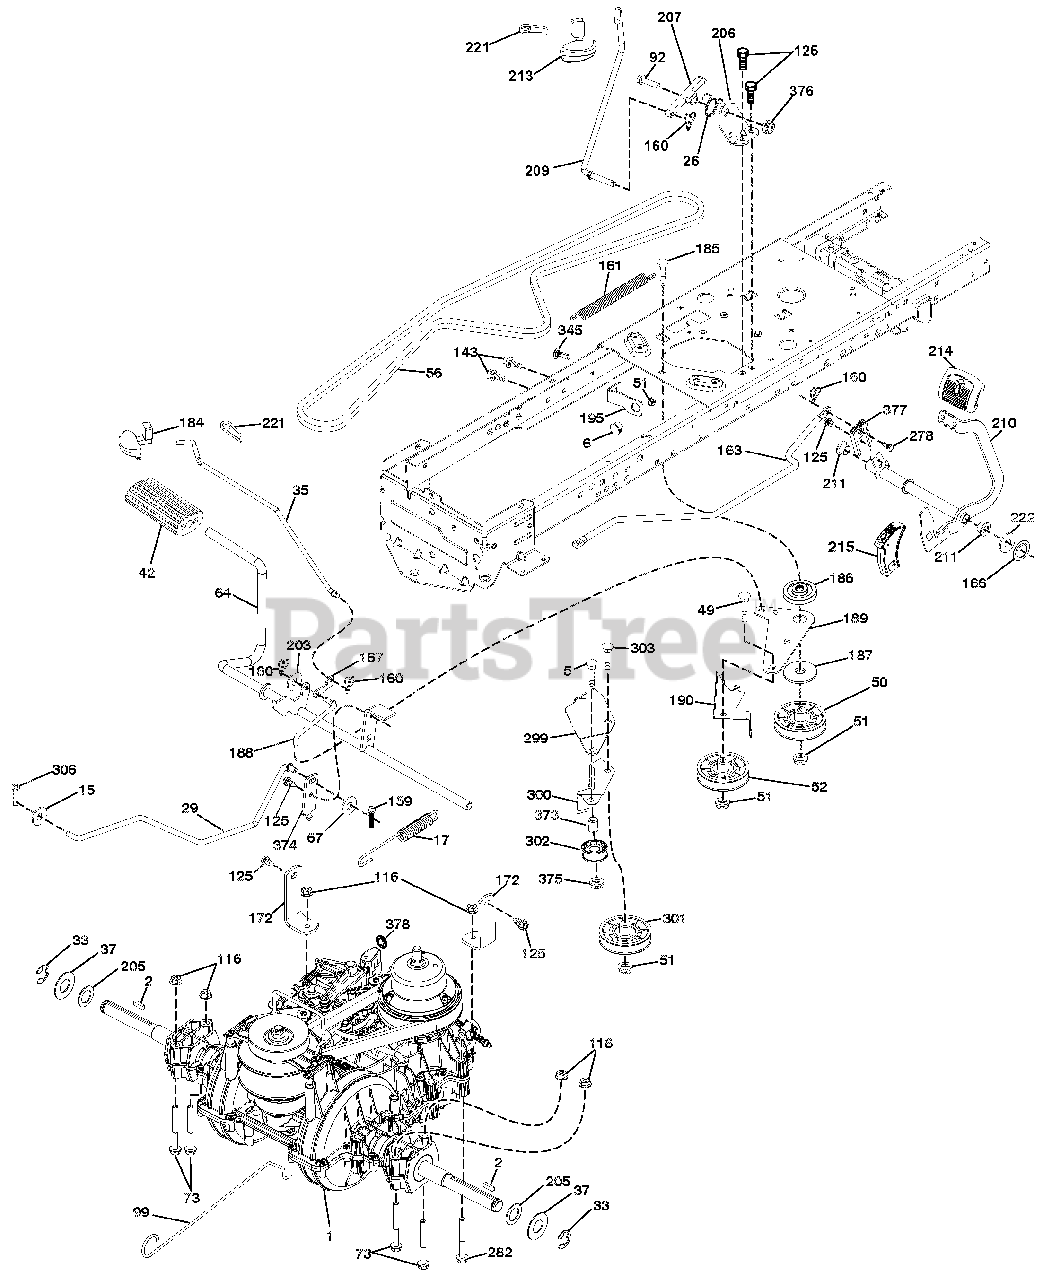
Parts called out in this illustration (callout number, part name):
1	TRANSAXLE, VARIATOR SD PEDAL (580486201)(ORDER PARTS FROM TRANSAXLE MANUFACTURER.)
2	KEY.SQUARE.2.0 X .1845/.1865
5	BOLT.HEX.HS.3/8-16.UNCX2-1/4
6	Bushing Snap Nyl Blk Fuel Line
15	WASHER.13/32 X 13/16 X 16 GA.
17	SPRING BRAKE
26	SPRING.RETURN.CRUISE
29	ROD BRAKE
33	E-RING.#5133-75
35	ROD.BRAKE.PARKING.LT.TEX
37	WASHER.HARDEN..793 X 1.637X060
42	COVER PEDAL BLK ROUND
49	BOLT.RDHD.3/8-16UNCX1-3/4.GR5
50	IDLER.FLAT.910"OFFSET
51	Nut, Hex, Flangelock 3/8-16
52	IDLER.V-GROOVE.910"OFFSET
56	BELT.DRIVE.100.97"
64	SHAFT ASM. PEDAL BRAKE
67	Washer 13/32 x 13/16 x 12 Ga.
73	BOLT.HEX.FLGHD.5/16-18.GR.5
92	Bolt, Hex Head 5/16-18 x 1-1/4
99	ROD.BYPASS
116	Nut, Lock Hex Flange 5/16-18 u
125	SCREW.5/16-18X3/4.SMGML.TAP/BL
143	SCREW.THDROL.5/16-18 X 1/2TYTT
159	PIN.COTTER.1/8 X 3/4.CAD.
160	RETAINER.CLIP(M).DIA.290
161	SPRING.RETURN.CLUTCH.6.75
163	ROD CONTROL PEDAL
166	NUT PUSH .625
167	LATCH.BRAKE.PARKING
172	STRAP TORQUE VARIATOR
184	HANDLE.PARKNG.BRAKE.LT.TEX.667
185	BOLT.RDHD.3/8-16UNC X2-3/4 GR5
186	SPACER.RETAINER
187	WASHER.13/32 X 2 X 10 GA.
188	LINK.CLUTCH.GROUND DRIVE
189	BELLCRANK.GROUNDRIVE.NSTG/NSTL
190	KEEPER.BELLCRANK.DRIVE.GROUND
195	BRACKET.BRAKE
203	Washer 11/32 x 11/16 x 16 Ga.
205	WASHER.25/32 X 1-5/8 X 16GA.
206	BRACKET MOUNT LATCH CRUISE
207	LATCH CONTROL CRUISE
209	ROD.CONTROL.CRUISE
210	WELDMENT PEDAL
211	BEARING.NYLON.BLK..629 ID.
213	KNOB.CONTROL.CRUISE
214	PAD PEDAL FORWARD
215	CAP PEDAL REVERSE
221	RETAINER.SPRING.CLIP.HANDLE
222	WASHER.21/32X1-1/4.10GA.N/PLTD
278	BOLT CRUISE VARIATOR
282	BOLT.HEX. 5/16-18 X 3 GR. 5
299	Bracket Mount Idler
300	Keeper Idler Rear
301	Pulley Idler V-Groove
302	PULLEY,IDLER.FLAT
303	Bolt Rdhd Sgnk 3/8-16 x 2-1/4
306	Pin Cotter 1/8 x 1 Cad
345	Bolt Rdhd Sht Sqnk 3/8-16 x 3/
373	SPACER.IDLER
374	ARM.BRAKE.CONTROL
375	Nut, Hex, Crownlock 3/8-16
376	Locknut, Hex 5/16-18
377	GEAR SECTOR CONTROL CRUISE
378	NUT PUSH
